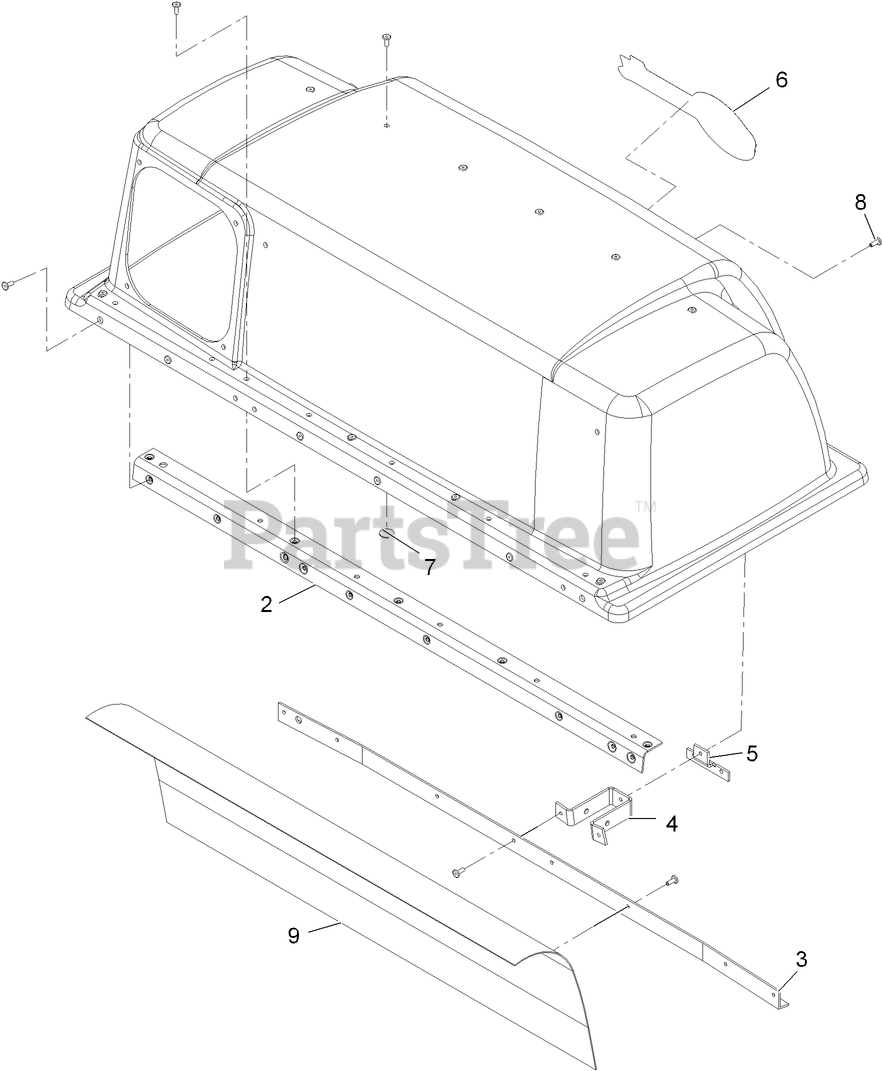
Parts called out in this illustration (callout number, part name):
2	STIFFENER-BAGGER, TOP
3	SUPPORT-SCREEN
4	ANCHOR-LATCH
5	REINFORCEMENT-LATCH
6	DECAL-EXMARK LOGO
7	WASHER-FLAT
8	RIVET-BLIND
9	SCREEN-BAGGER
